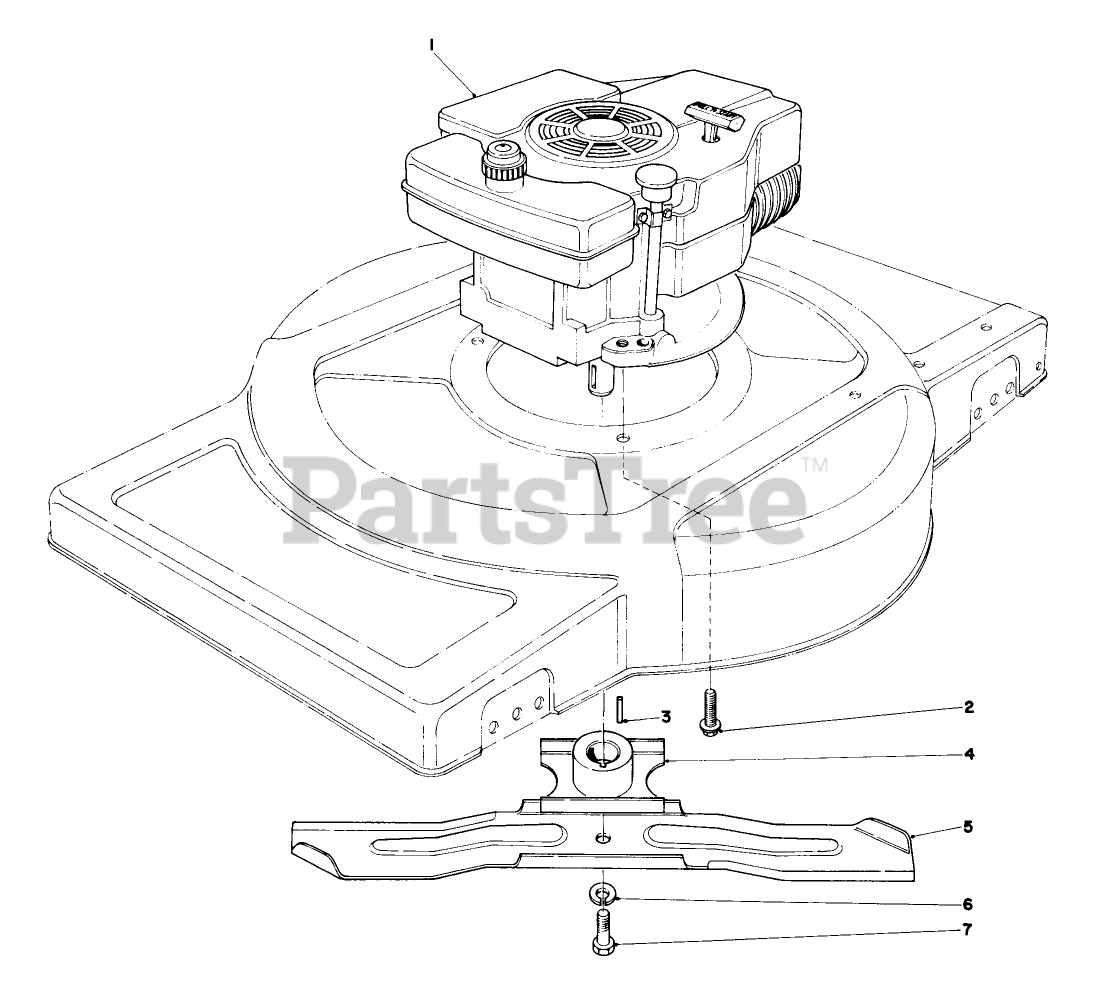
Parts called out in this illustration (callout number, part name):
1	Engine
3	KEY-SQUARE
6	WASHER-LOCK
7	BLADE SCREW
